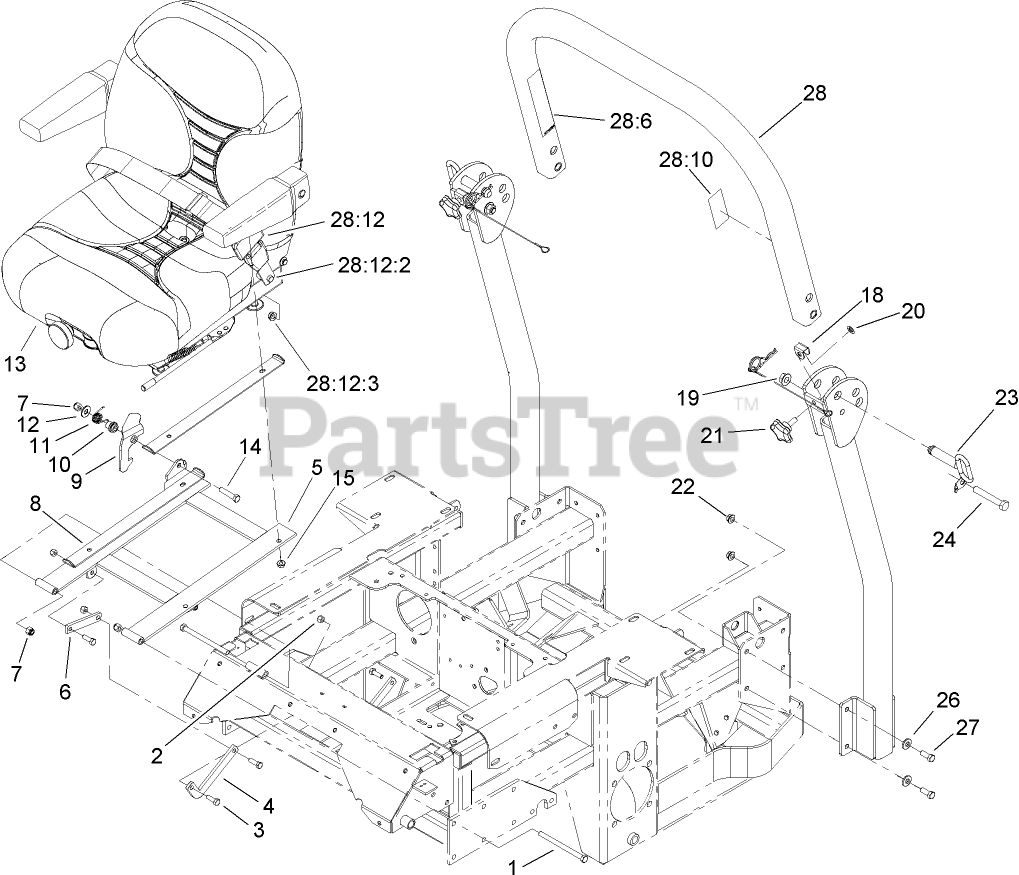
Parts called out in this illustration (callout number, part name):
1	SCREW-HH
2	NUT-LOCK, NI
3	SCREW-HH
4	LINK-SEAT STOP, LOWER
5	FRAME-SEAT
6	LINK-STOP, SEAT
7	NUT-LOCK, NI
8	STOP-SEAT
9	CATCH-LATCH, SINGLE
10	BUSHING-LATCH, SEAT
11	SPRING-TORSION, LATCH
12	WASHER-FLAT
13	SEAT-SUSPENSION
14	SCREW-HH
15	NUT-HF
19	NUT-HF
20	NUT-PUSH
22	NUT-HHF, WHIZ
23	PIN-FOLD, ROPS
24	SCREW-HH
26	WASHER-BELLEVILLE
27	SCREW-HH
28	ROPS ASM
28:6	DECAL-WARNING
28:10	DECAL-ROPS
28:12	SEATBELT KIT
28:12:2	SCREW-HH
28:12:3	NUT-LOCK, NI
